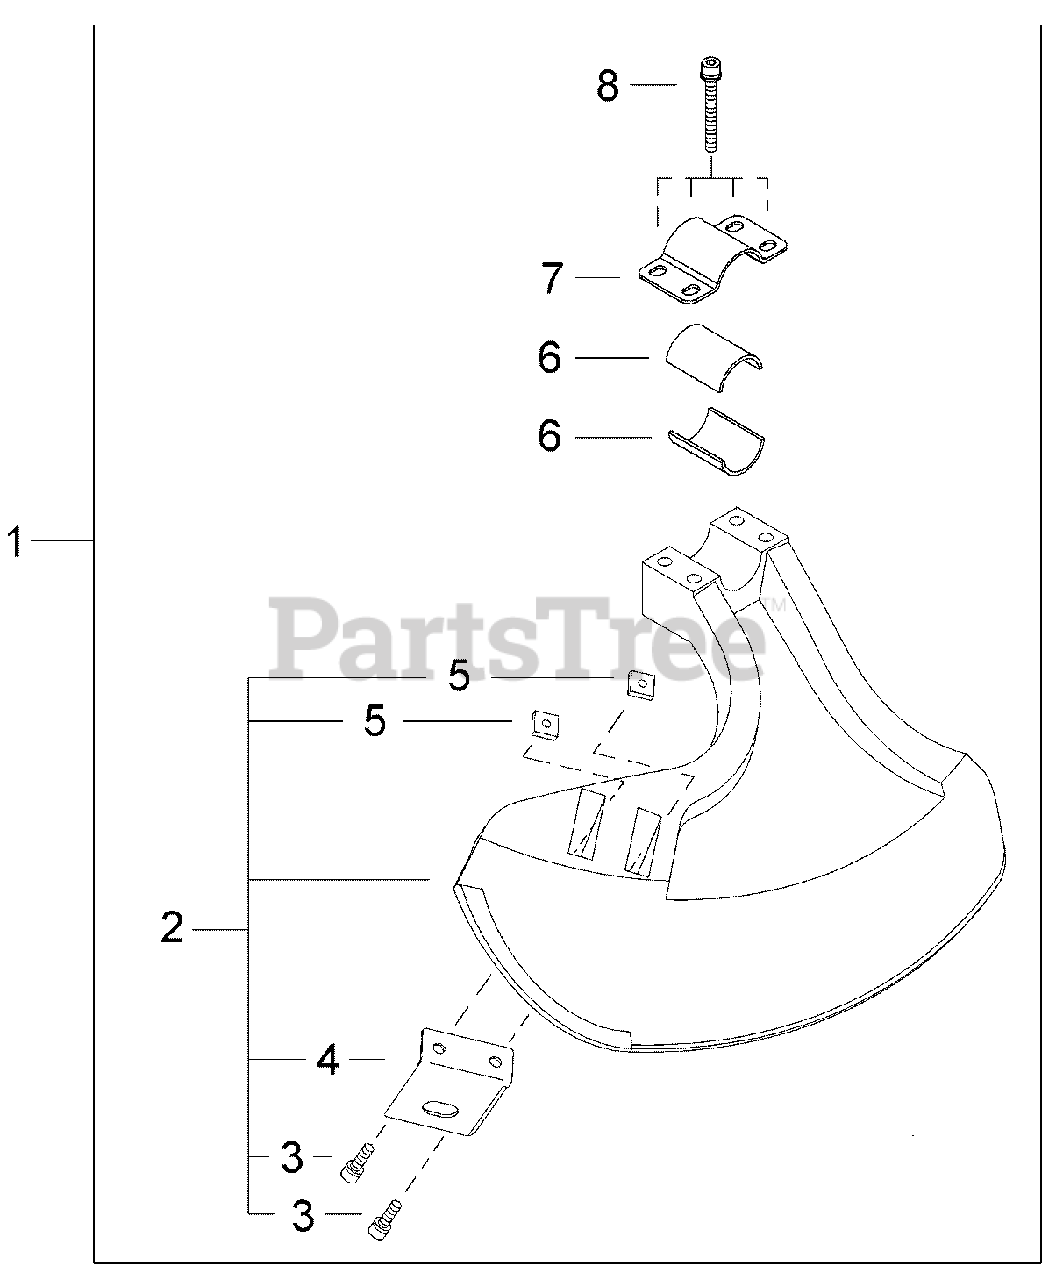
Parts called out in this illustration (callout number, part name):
1	DEBRIS SHIELD KIT
2	DEBRIS SHIELD ASSY
3	SCREW - 5X16
4	KNIFE, TRIMMER LINE
5	NUT - 5
6	SPACER
7	CLAMP - UPPER
8	SCREW - 5X45
